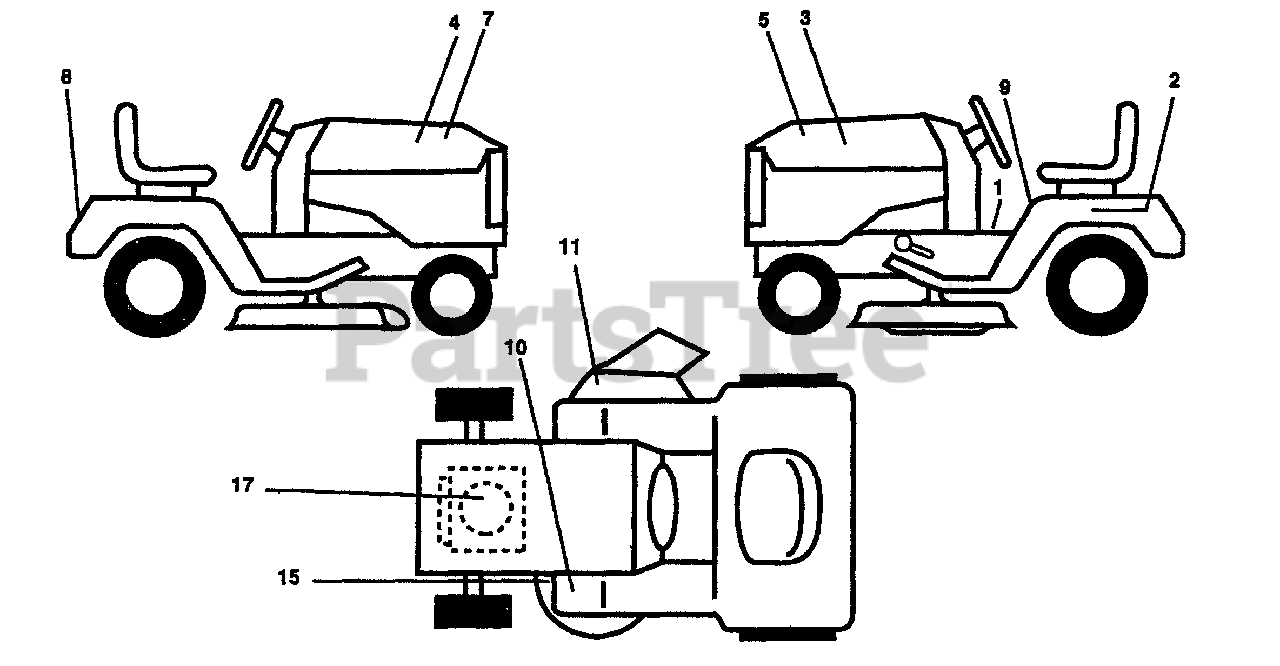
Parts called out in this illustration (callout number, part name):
1	Decal Instruction Dash
2	Decal Caution Battery
3	Decal Hood LH
4	Decal Hood RH
5	Decal Ins Hd LH
7	Decal Ins Hd RH
8	Decal Fender Husq
9	Decal Caution Fender
10	Decal Clutch/brake
11	Decal Warning
15	Decal V-Belt Schematic
17	Decal B & S 15.5 Diamond Engine
